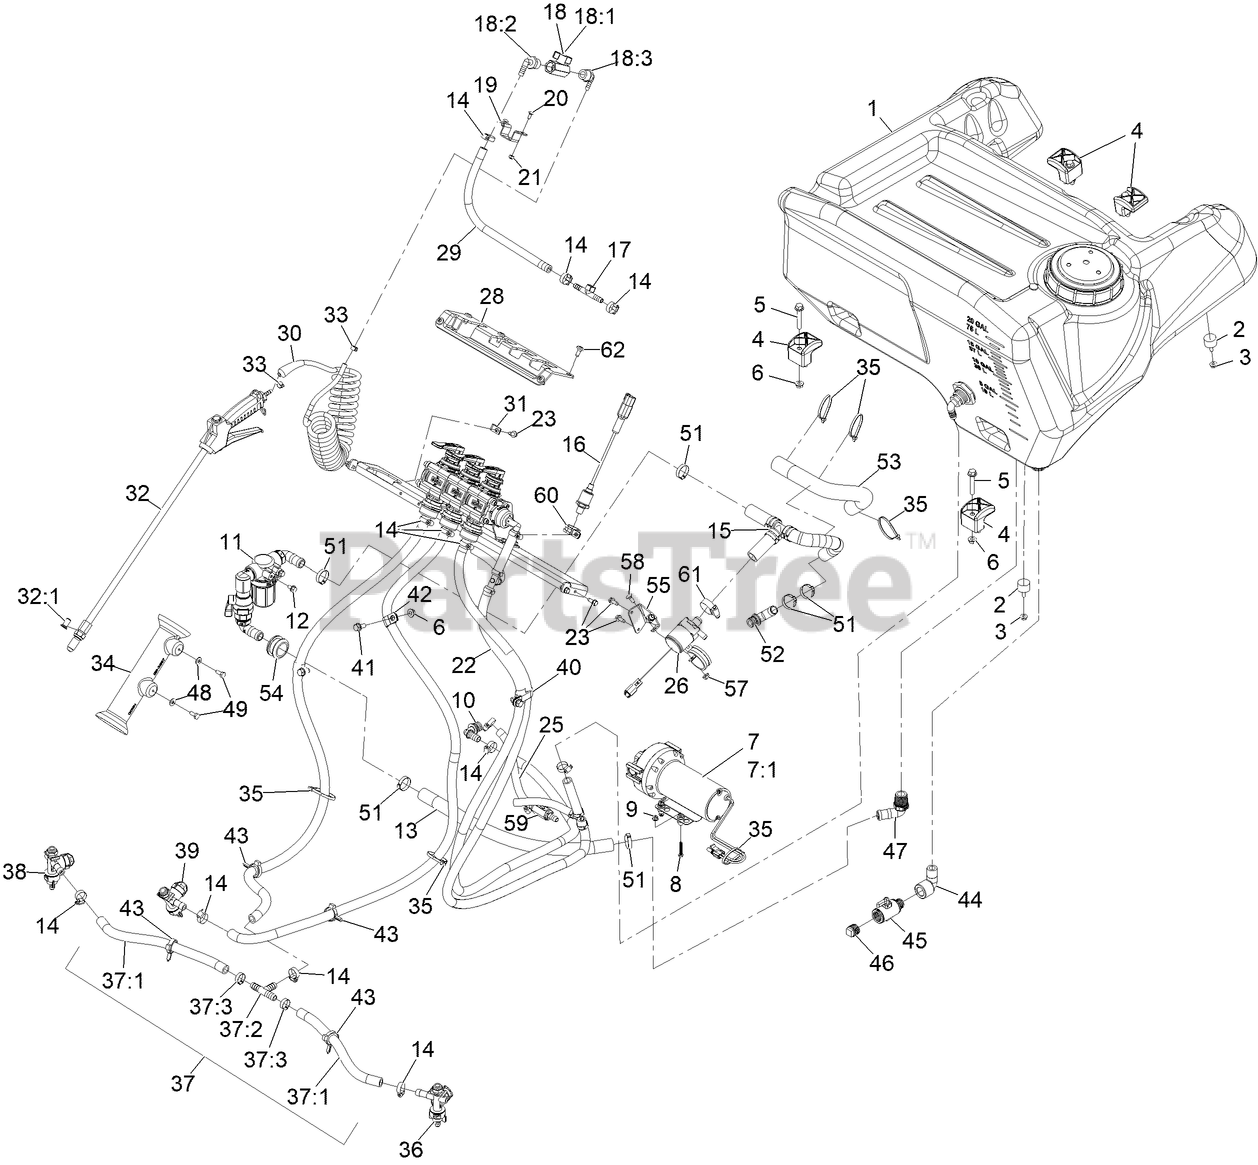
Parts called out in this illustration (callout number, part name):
1	Tank-Sprayer
5	SCREW-HHF
7	Pump-Diaphragm, 3.8 GPM
7:1	KIT-DIAPHRAM PUMP
8	SCREW-SHWH
10	FITTING-ELBOW, BARBED
11	STRAINER ASM
12	SCREW-HHF
13	HOSE-WATER
14	CLAMP-HOSE
15	ASM-, 3/4 Pvc Reinforced Water Hose
16	TRANSDUCER-PRESSURE
17	FITTING-TEE
18	Wand Control ASM
18:1	VALVE-BALL
18:2	FITTING-ELBOW-90
18:3	FITTING-ELBOW-90
19	BRACKET-VALVE
20	BOLT-CARR
21	NUT-LOCK, NI
22	Manifold-Valve, Control ASM
23	SCREW-HWH
25	Hose-Water
26	Pump-Centrifugal
28	Cover-Controls
29	HOSE-WATER, 3/8 PVC RED
30	Hose-Coiled, 04X15Ft
31	CLAMP-R
32	SPRAY WAND ASM
32:1	STRAINER-NOZZLE, 50M 5PSI
34	HOLDER-WAND
35	TIE-CABLE
36	LEFT NOZZLE SUB ASM
37	HOSE ASM
37:1	HOSE-WATER
37:2	FITTING-TEE
37:3	CLAMP OETIKER 0.716"" CLOSED 0.826"" OPEN
38	RIGHT NOZZLE SUB ASM
39	CENTER NOZZLE SUB ASM
41	SCREW-HHF
42	CLIP-LOOM
43	CLAMP-HOSE
44	ELBOW-90 DEG
45	MICROVALVE
47	ELBOW-HOSEBARB
48	WASHER-FLAT
49	SCREW-HH
52	FITTING-ELBOW
53	SLEEVE-CORRUGATED, SPLIT
54	GROMMET
55	Brkt-Recir Pump
58	SCREW-CARR
59	Valve-3/8 Check
60	R-Clamp
61	CLAMP-HOSE
62	SCREW-SHOULDER
